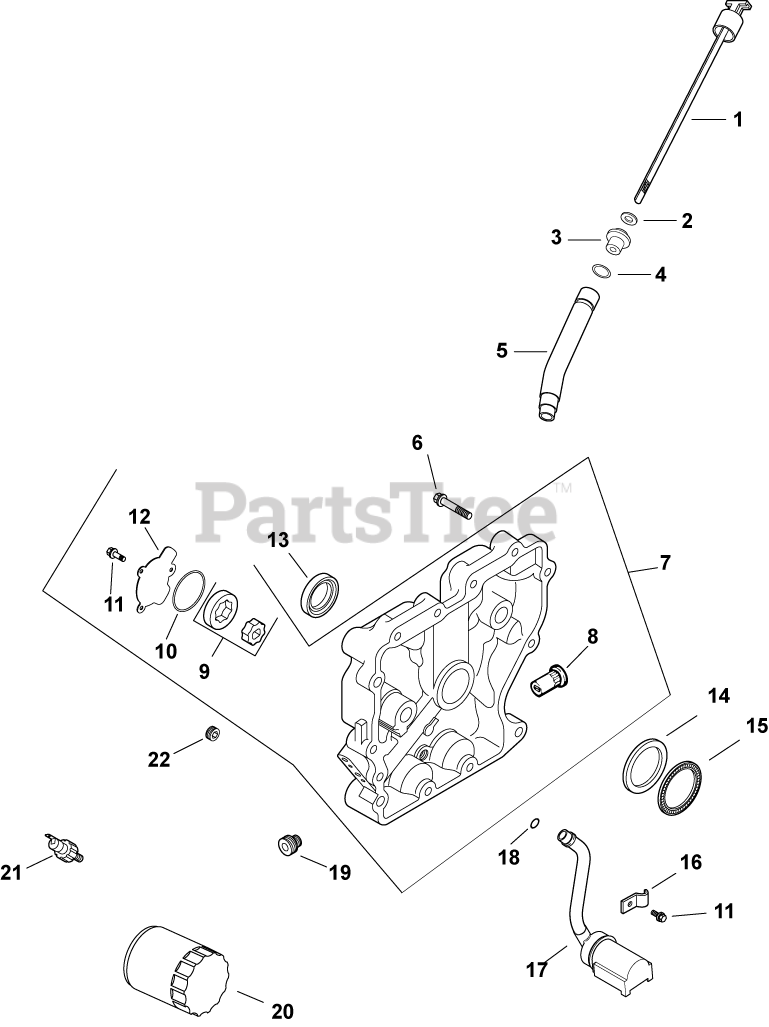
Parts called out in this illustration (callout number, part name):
3	SEAL USE 25 032 13-S
5	TUBE, OIL FILL
6	SCREW, FLG M8X1.25X45
7	CLOSURE PLATE ASSEMBLY - DISCONTINUED
8	VALVE, OIL PRESSURE RELIEF
9	PUMP ASSEMBLY, OIL
10	O-RING (1.78" DIA)
11	SCREW,FLG THD FRM M5X0.8X16-(#25086398S)
12	COVER, OIL PUMP
13	SEAL, OIL
14	WASHER, THRUST (1MM)
15	BEARING, THRUST
17	KIT, OIL PICK-UP
18	O-RING (.5" DIA)
19	NIPPLE, OIL FILTER
20	OIL FILTER
21	SENSOR, OIL PSI
22	PLUG, CTSK PIPE 1/8"
